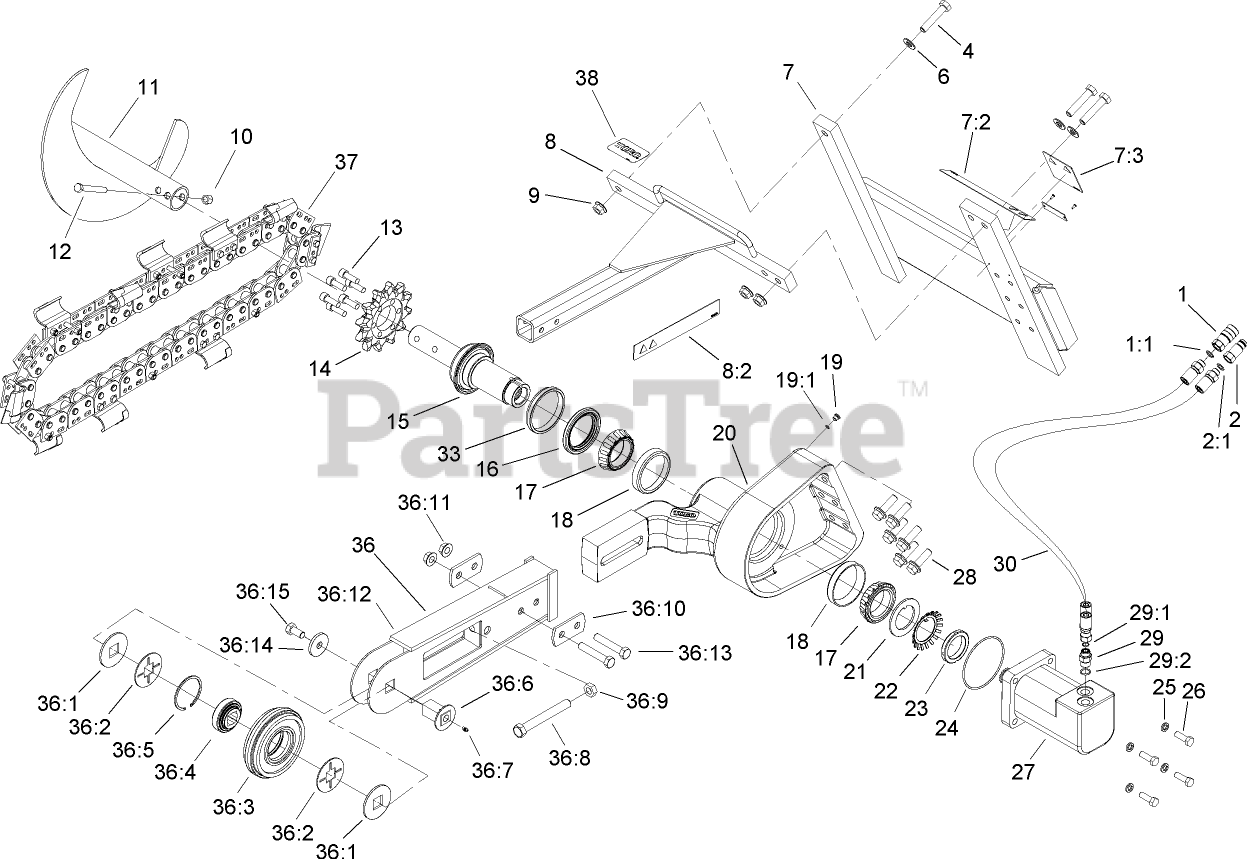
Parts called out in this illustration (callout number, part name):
1	COUPLER-FEMALE
1:1	SEAL KIT
2	NIPPLE-CONNECTOR
2:1	SEAL KIT
4	SCREW-HH
6	WASHER-FLAT
7	MOUNT ASM
7:2	DECAL-DANGER
7:3	DECAL-DANGER
8	SAFETY BAR ASM
8:2	DECAL-DANGER
9	NUT-FLANGE
10	NUT-LOCK, NI
11	AUGER ASM
12	SCREW-HH
13	SCREW-HSH
14	SPROCKET-TRENCHER
15	SHAFT-TRENCHER
16	SEAL-SHAFT
17	CONE-BEARING
18	CUP-BEARING
19	PLUG ASM
19:1	O-RING
20	MOUNT-BOOM
21	WASHER-TONGUED
22	WASHER-LOCK, BEARING
23	NUT-LOCK, BEARING
24	O-RING
25	WASHER-LOCK
26	SCREW-HH
27	MOTOR-HYD, HIGH SPEED
29	FITTING-STRAIGHT
29:1	O-RING
29:2	O-RING
30	HOSE ASM
33	SPACER
36	BOOM ASM
36:1	CAP-ROLLER
36:2	SPACER-ROLLER
36:3	ROLLER-NOSE
36:4	BEARING
36:5	RING-RETAINING
36:6	PIN ASM (only on: 22471)
36:7	FITTING-GREASE
36:8	BOLT-ADJUSTMENT
36:9	NUT-JAM
36:10	PLATE-SUPPORT
36:11	NUT-FLANGE
36:12	BOOM ASM
36:13	SCREW-HH
36:14	WASHER
36:15	SCREW-HH
37	TRENCHER CHAIN ASM
38	DECAL
